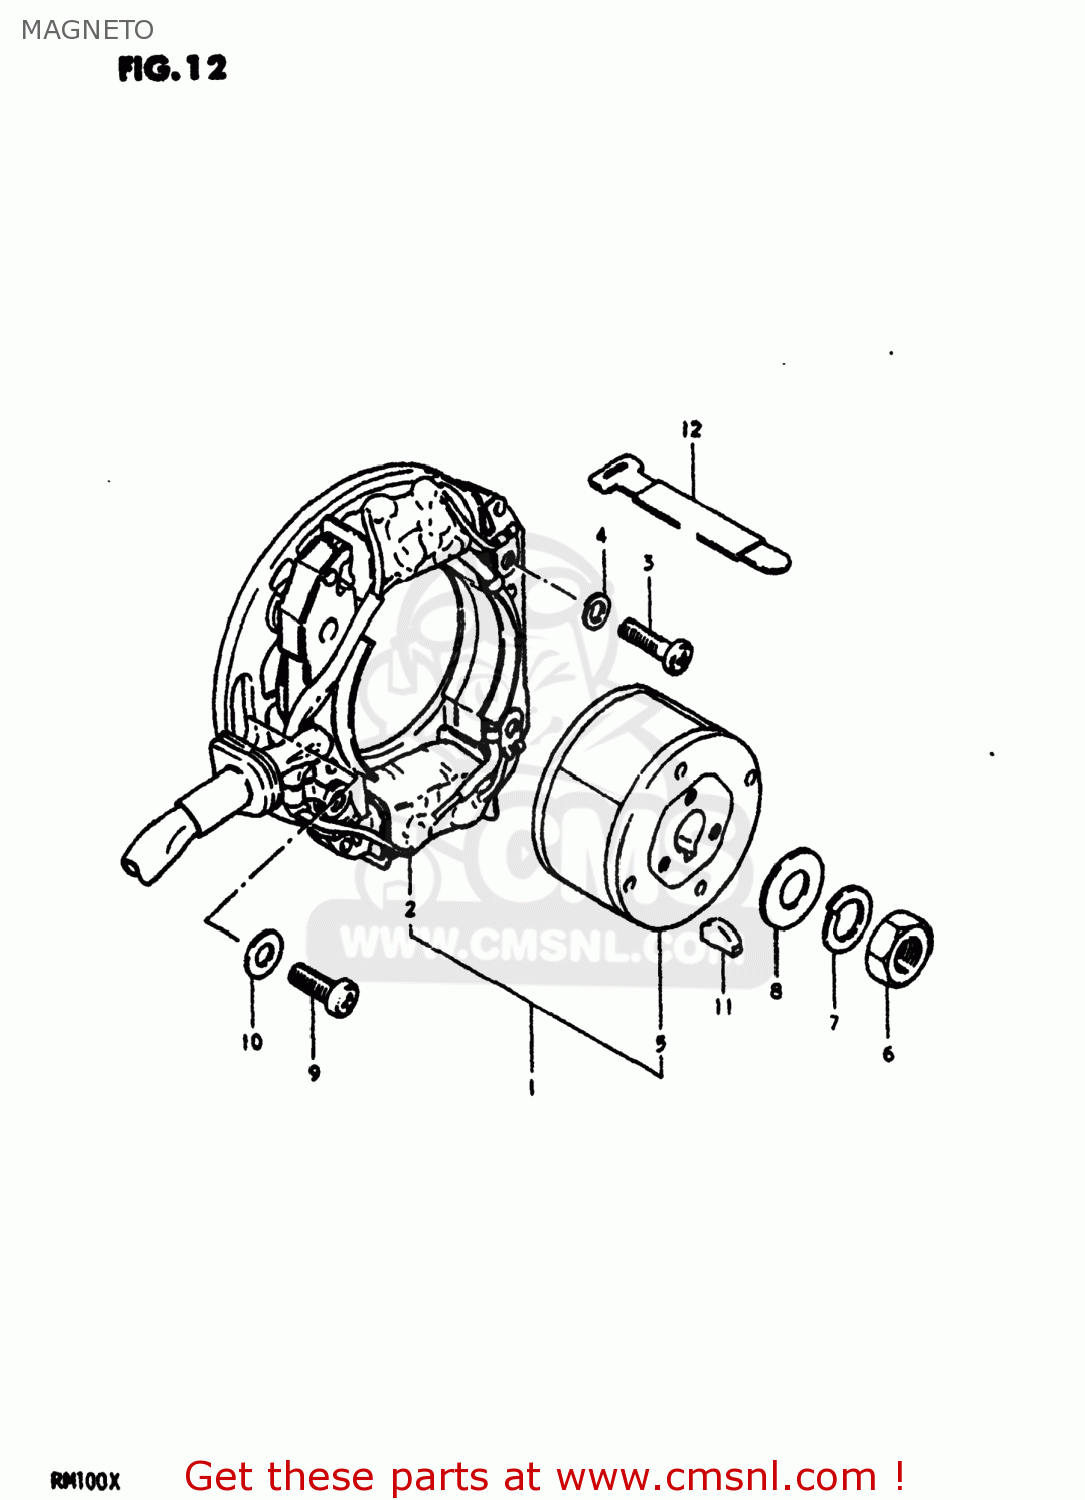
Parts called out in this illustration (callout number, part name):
1	MAGNETO ASSEMBLY
2	STARTER ASSY
3	SCREW 5X20
4	LOCK WASHER
5	ROTOR ASSEMBLY
6	NUT (10MM)
7	LOCK WASHER
8	WASHER
9	SCREW
10	WASHER
11	KEY 4MM
12	CLAMP
